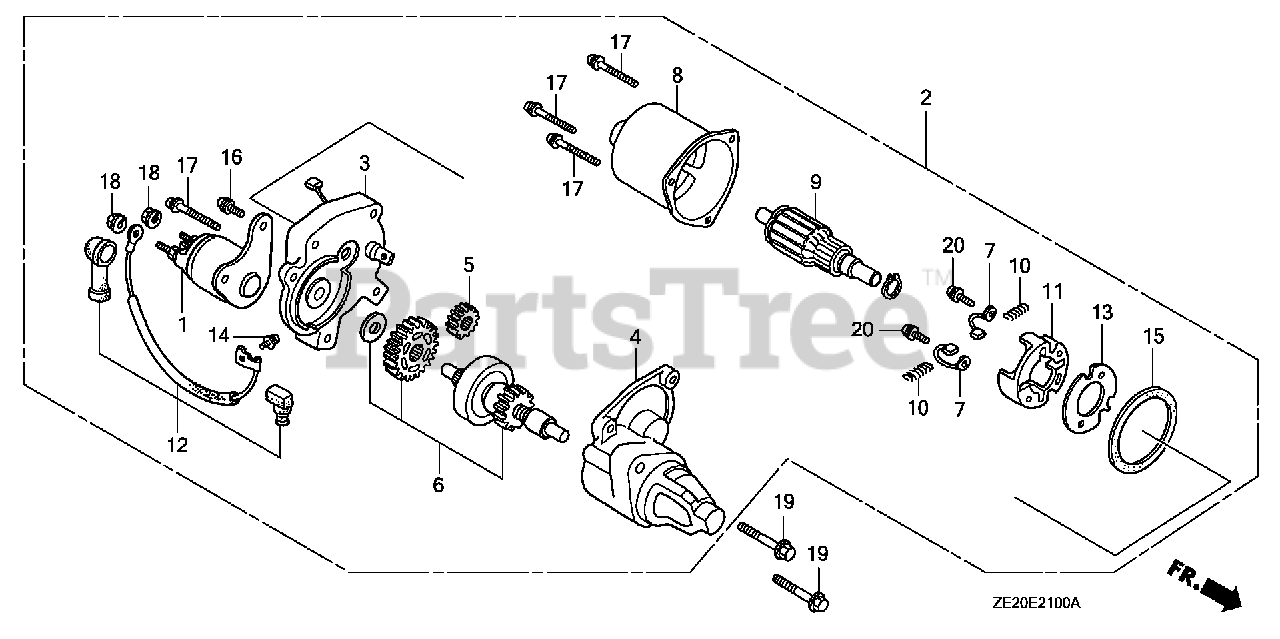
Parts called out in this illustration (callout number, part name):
1	CONTACTOR ASSY.
1	CONTACTOR ASSY. (NOT AVAILABLE)
2	STARTER MOTOR UNIT
3	BRACKET, CENTER
4	BRACKET, FR.
5	GEAR, DRIVE PINION
6	CLUTCH, OVERRUNNING
10	SPRING, BRUSH RETURN
11	HOLDER, BRUSH
12	WIRE, WATER COVER
14	SCREW-WASHER (4X6)
16	SCREW-WASHER (5X14)
17	SCREW-WASHER (5X32)
18	NUT-WASHER (6MM)
19	BOLT, FLANGE (8X40)
20	SCREW-WASHER (4X14)
